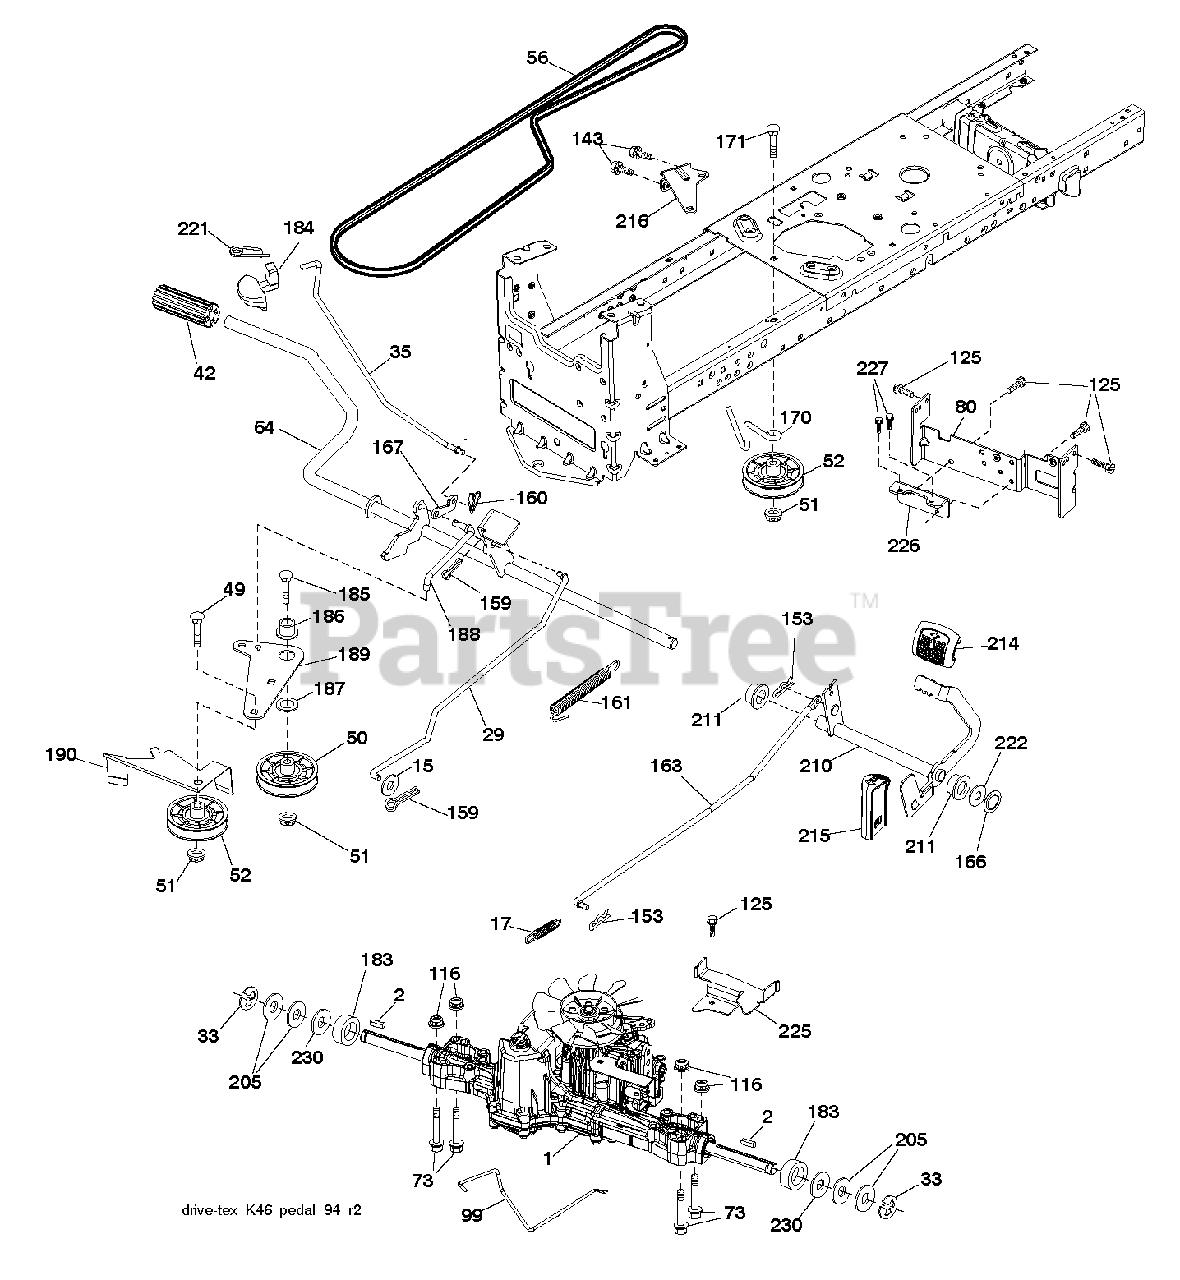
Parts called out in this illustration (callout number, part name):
2	SQUARE KEY
15	WASHER
17	SPRING, BREAK
29	ROD.BRAKE.K46
33	E-RING LT
42	PEDAL COVER T
50	IDLER.FLAT.910.OFFSET
52	IDLER.V-GROOVE.910.OFFSET
64	SHAFT.ASM.PEDAL.BRK.CN
99	ROD.SPRING.BYPASS.K46.LT.Z
116	NUT LOCK HEX FLANGE 5/16-18
125	SCREW
143	SCREW LT
159	COTTER PIN
160	RETAINER CLIP
161	SPRING, RETURN LT
166	NUT.PUSH.625
167	LATCH BRAKE PARKING
170	KEEPER.V-IDLER.CENTER.
183	SPACER AXLE
186	SPACER.RETAINER
188	LINK.CLUTCH.GROUND DRI
189	BELLCRANK.GRDDRIVE.NST
190	KEEPER.BELLCRANK.DRIVE
210	ROCKER.ASM.PEDAL.CONTR
211	BEARING RER
214	PAD PEDAL FORWARD
215	PEDAL.REVERSE.TEX.GT.4
216	BRKT.PULLEY.IDLER.WTEX
221	RETAINER.SPRING.CLIP.H
222	WASHER 21/32 X 1-1/4 X 10 GA.
225	KEEPER.BELT.TRANSAXLE.
226	BRACKET MOUNT TORQUE
